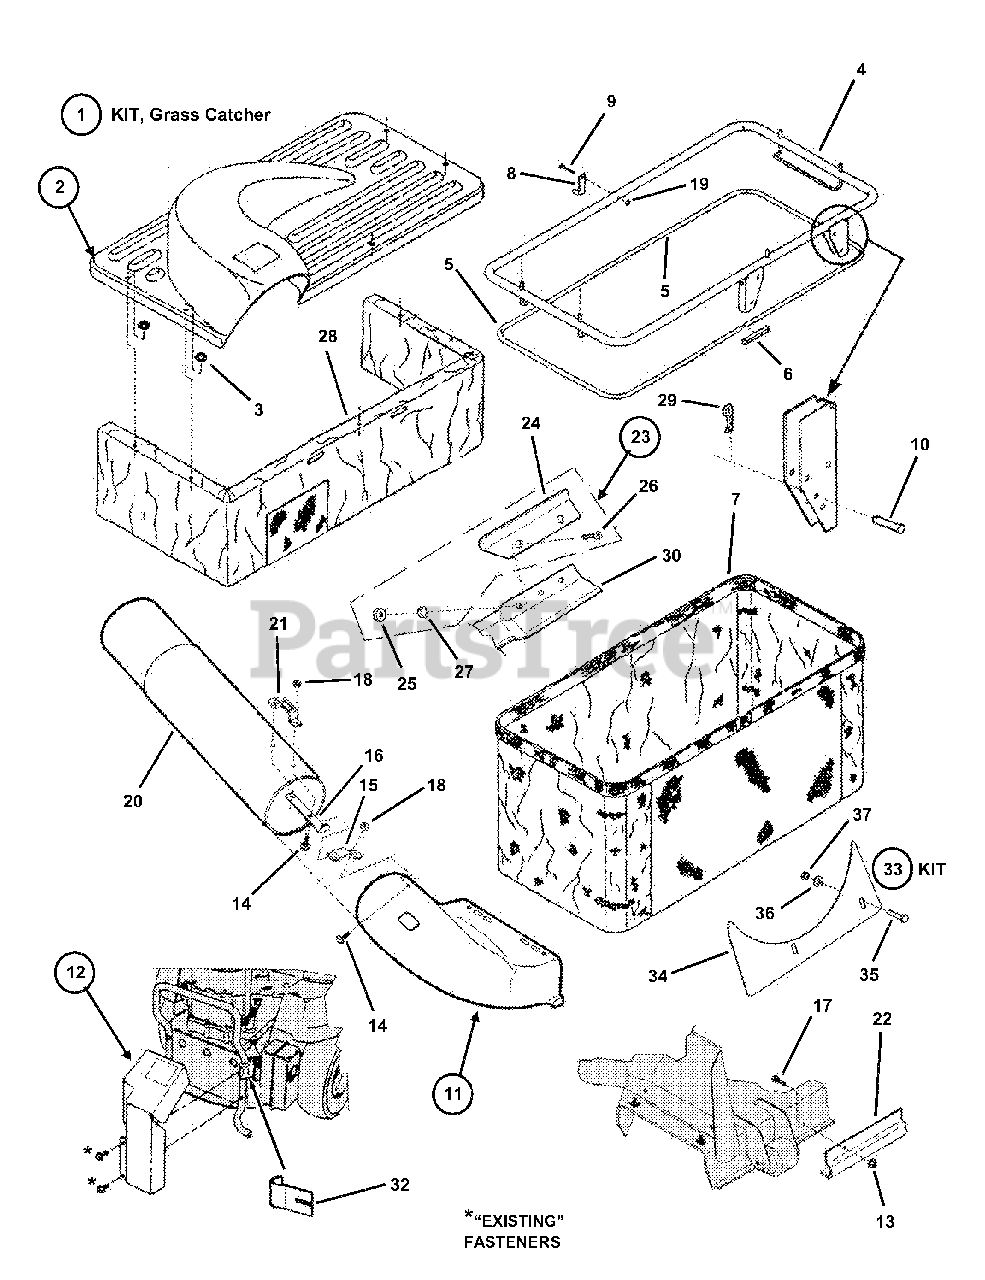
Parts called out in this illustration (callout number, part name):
1	KIT, Grass Catcher (42" Models)
2	TOP, Container
3	WASHER, 5/16" Faceted
4	FRAME, Weldment
5	ROD, Bag
6	CONNECTOR, Bag Rod
7	BAG, Grass
8	LATCH, Top
9	SCREW, #10-32 x 1-3/8" Hex Head Machine
10	PIN, 5/16 x 1-11/16" Clevis
11	ADAPTER, Deck
12	ASSEMBLY, Debris Shield
13	NUT, 5/16-18 Hex Flange Lock, Grade 5
14	BOLT, 1/4-20 x 5/8" Flat Head Square Neck, Grade 2
15	LATCH, Tube
16	BASE, Handle
17	SCREW, 5/16-18 x 3/4" Pan Head Machine
18	NUT, 1/4-20 Hex Flange Lock, Grade 5
19	NUT, #10-32 Hex Nyloc
20	TUBE, Grass (38" long)
21	HANDLE, Tube
22	BAFFLE, 42" Deck
23	KIT, Air Lift
24	EXTENSION, Air Lift
25	NUT, 5/16-24 Hex
26	SCREW, 5/16-24 Oval Head Machine
27	WASHER, 5/16" Internal Tooth Lock
28	DUST SKIRT
29	PIN, 3/32 x 1-1/2" Hair
30	BLADE, 21" Air Lift
32	BRACKET, Bumper Reinforcement
33	KIT, Catcher Debris Shield
34	SHIELD, Debris
35	BOLT, 1/4-20 x 1-1/2" Hex
36	WASHER, 1/4" Flat
37	NUT, 1/4-20 Hex Top Lock
